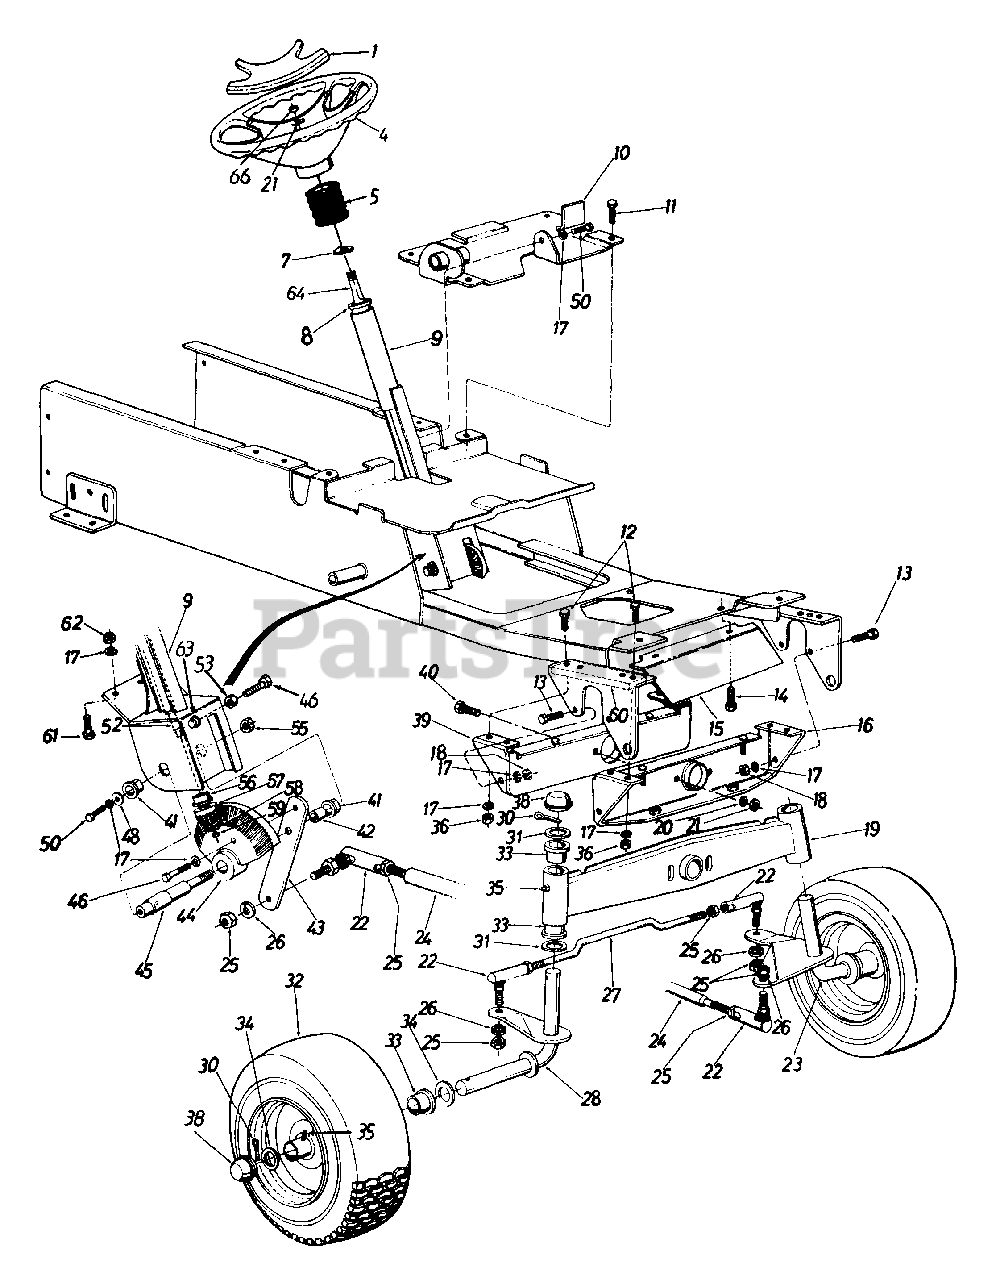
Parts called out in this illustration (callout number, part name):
1	Steering Wheel Insert
2	Hex Cent. L-Nut 5/16-24 Thd.
3	Bell-Wash. 5/16" I.D.
4	Steering Wheel
5	Steering Bellow
7	Wave Wash. .660" I.D. x .88" O.D.
8	Ball Brg. .63" I.D. x 1.38" O.D.
9	Steering Column Ass'y.
10	Dash Panel Base Plate Ass'y.
11	Hex Self-Tap Scr. 3/8-16 x .75" Lg.
12	Hex Bolt 3/8-16 x 1.50" Lg.
13	Hex Bolt 3/8-16 x 1.00" Lg.
14	Hex Wash. S.F. Tap Scr. 3/8-16 x 1.25" Lg.
18	Hex Nut 3/8-16 Thd.
19	Pivot Bar Ass'y.
20	Bell-Wash. 3/8" I.D.
21	Hex Cent. L-Nut 3/8-16 Thd.
22	Drag Link End
23	Axle Ass'y. - L.H.
24	Drag Link
25	Hex Nut 1/2-20 Thd.
26	L-Wash. 1/2" I.D.
27	Tie Rod
28	Axle Ass'y. - R.H.
30	Cotter Pin 3/16" Dia. x 1.50" Lg.
31	Fl-Wash. 1.00" I.D. x 1.62" O.D.
33	Flange Brg. 1" I.D.
34	Fl-Wash. 1" I.D. x 1.25" O.D.
35	Grease Fitting
36	Hex Nut 3/8-16 Thd.
38	Dust Cover
41	Flange Brg. w/Flats .753" I.D.
42	Steering Gear Shaft Spacer
43	Steering Arm
44	Bevel Gear
45	Steering Gear Shaft
46	Hex Bolt 3/8-16 x 1.50" Lg.
48	Fl-Wash. .406" I.D. x 1.25" O.D.
50	Hex Bolt 3/8-16 x .75" Lg.
52	Steering Shaft
53	Hex Jam Nut 3/8-16 Thd.
55	Hex Ins. L-Nut 1/2-20 Thd.
56	Hex Flange Brg. .630 I.D.
57	Pinion Gear
58	Fl-Wash. 3/8" Dia.
59	Hex Cent. L-Nut 5/16-24 Thd.
62	Hex Nut 3/8-24 Thd.
63	Cap
64	Steering Shaft
